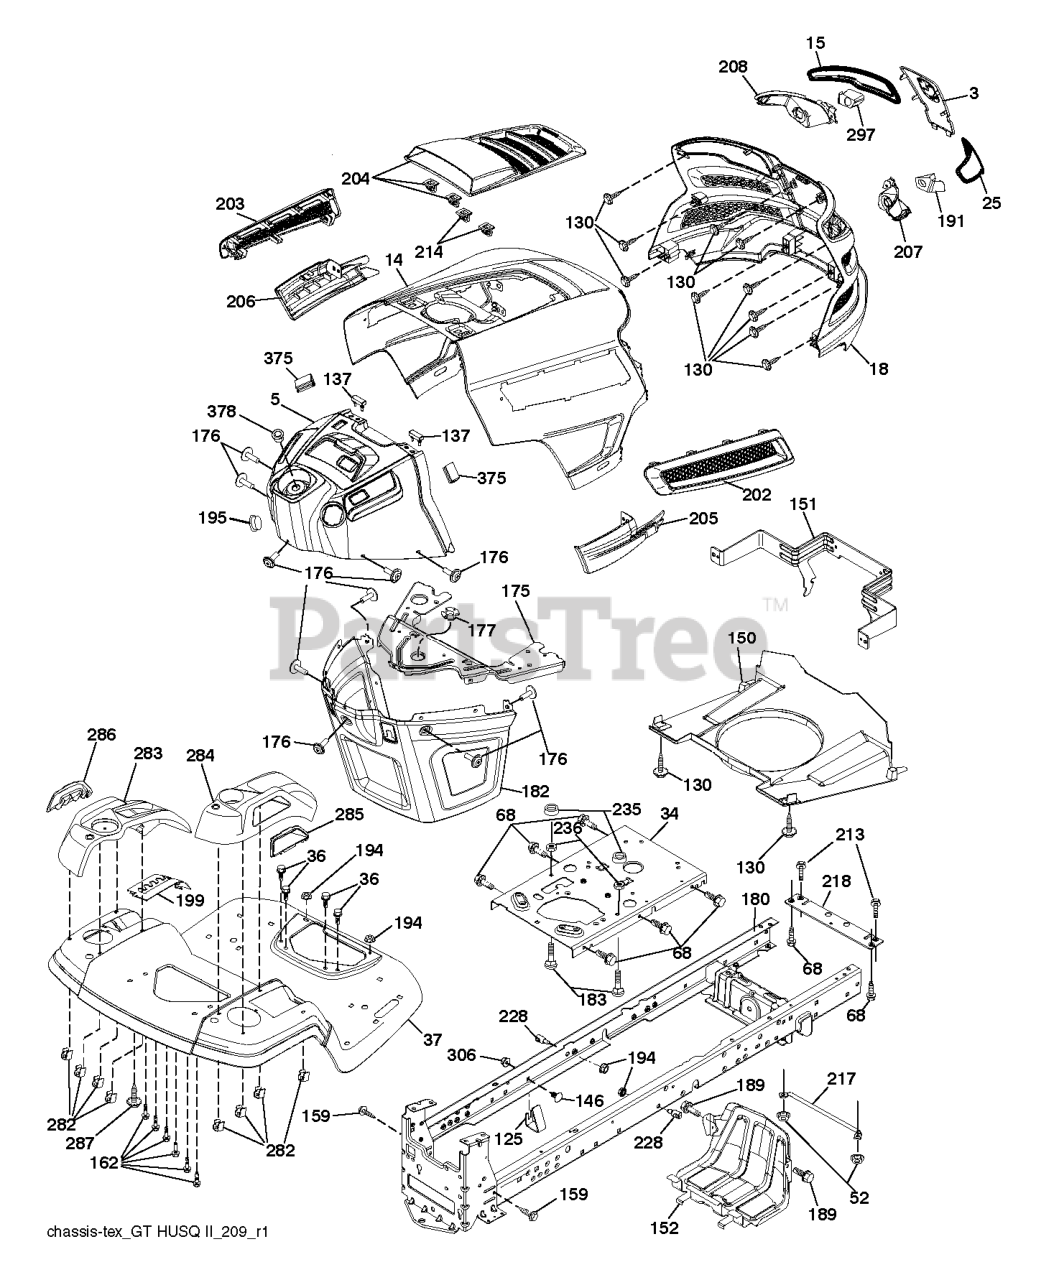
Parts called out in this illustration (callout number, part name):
3	APPLIQUE.SUBASM.GT.HUSQ.II
5	DASHBOARD.UPPER.ASM.GT2.X498
14	HOOD.ASM.HUSQVARNA.GT.TEX.ORAN
15	LENS.HEADLIGHT.LH.GTII.2011
25	LENS.HEADLIGHT.RH.GTII.2011
34	PLATE.ENGINE.WELDED.CHASSIS
36	SCREW 5/16"
37	FENDER.TLT.FS.W/CUPHLD.ORANGE
125	CLIP.FUEL.LINE
137	BUMPER DASH
146	BOLT.RDHD.SHT.SQNK.3/8-16X5/8
150	AIR DUCT.GTV2(1.66"RING HEIGHT
151	BRACKET.PIVOT.HOOD.GT.HUSQ.II
152	SHIELD.BROWNING.PNT.GT.V2
159	SCREW, 3/8-16X3/4
175	PLATE.PNT.CROSSMEMBER.HUSQ/PRE
176	SCREW.#10-24X5/8.RN.QU
177	BUSHING STEERING
180	CHASSIS
182	DASH LOWER.HUSQ.PRED NO CRUISE
189	SCREW
191	INSERT.REFLECTIVE.RH.HUSQ.GTII
195	PLUG.HOLE.DASH.LOWER.12V.BLK
199	PLATE.DECK.LIFT.HUSQ.LT
202	VENT.SIDE.RH.GT.HUSQ.II.
203	VENT.SIDE.LH.GT.HUSQ.II.498
204	VENT.TOP.ASM.HUSQ.GT2
205	SIDE.TRIM.RH.GT.HUSQ.II
206	SIDE.TRIM.LH.GT.HUSQ.II.GRAY
207	HEADLIGHT.CUP.BEZEL.HUS.GT2.RH
208	HEADLIGHT.CUP.BEZEL.HUS.GT2.LH
213	SCREW HEXAGON HEAD SCREW 5/16-
214	CLIP.RETAINER.TINNER.
217	ROD.PIVOT.HOOD
218	X-PIECE.HOOD.STOP.NON/
228	STUD.W/"D"ANTI-ROTATION
236	NUT.CENTERLOCK.5/16-
282	CLIP.RETAINER.CONSOLE.LT.HUSQ
283	CONSOLE.ASM.LFT.RSF.HUSQ.LT
284	CONCOLE.CNTRL.PDL.HUSQ.LT.498
285	CONSOLE INSERT RH
286	CONSOLE.INSRT.LH.HUSQ.LT.BLACK
287	SCREW 1/4X20
297	INSERT.REFLECTIVE.LH.HUSQ.GTII
306	NUT LOCK FLG 3/8-16 UNC
375	BUMPER CLIP-ON. DASH 1"
378	BUSHING FLANGE; PLASTIC
